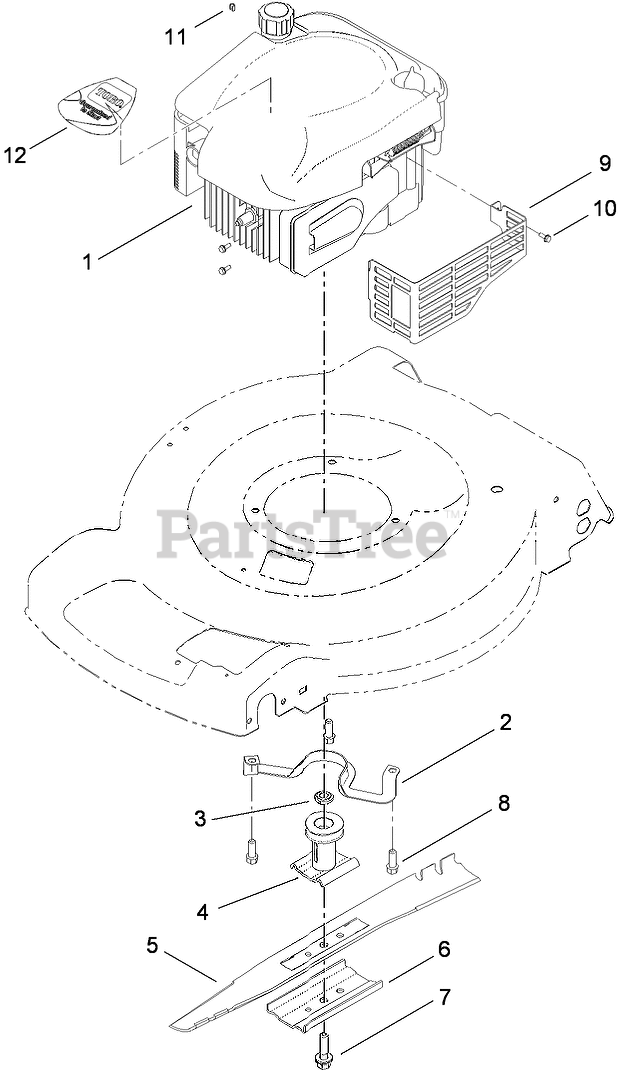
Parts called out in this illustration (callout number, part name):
2	Guide-Belt
3	Spacer-Driver
4	DRIVER-BLADE
5	BLADE-22 INCH
6	SUPPORT-BLADE
7	BOLT-BLADE
8	SCREW-TAPTITE
9	SHIELD-MUFFLER
10	SCREW-TAPTITE
11	STOP-ROPE
